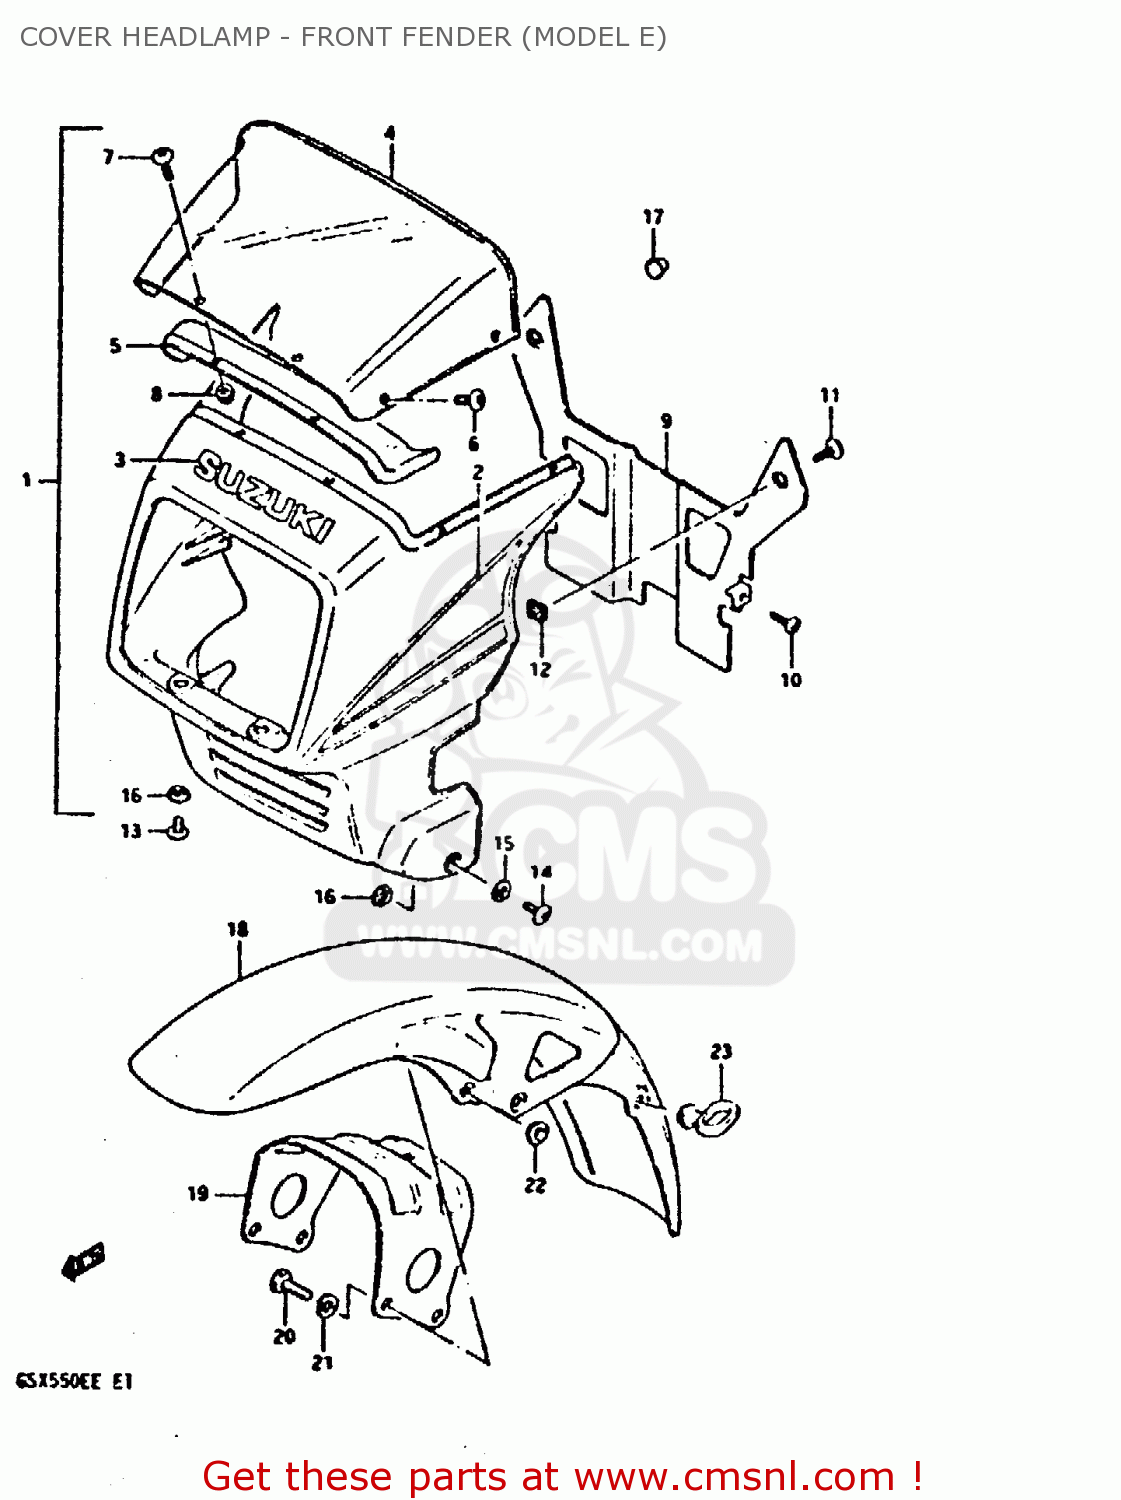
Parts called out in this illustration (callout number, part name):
1	COVER ASSY, HEADLAMP
2	TAPE SET
3	EMBLEM
4	WINDOW,COVER HEADLAMP
5	COVER,HEADLAMP,UPPER
6	SCREW(5X12)
7	SCREW
8	NUT
9	PLATE,HEADLAMP COVER
10	SCREW
11	SCREW
12	NUT
13	SCREW 6X12
14	SCREW 6X12
15	WASHER (6.5X18X1.6)
16	WASHER
17	PLUG
18	FENDER,FRONT
19	BRACE,FRONT FENDER
20	BOLT
21	LOCK WASHER
22	WASHER
23	GUIDE,CABLE
